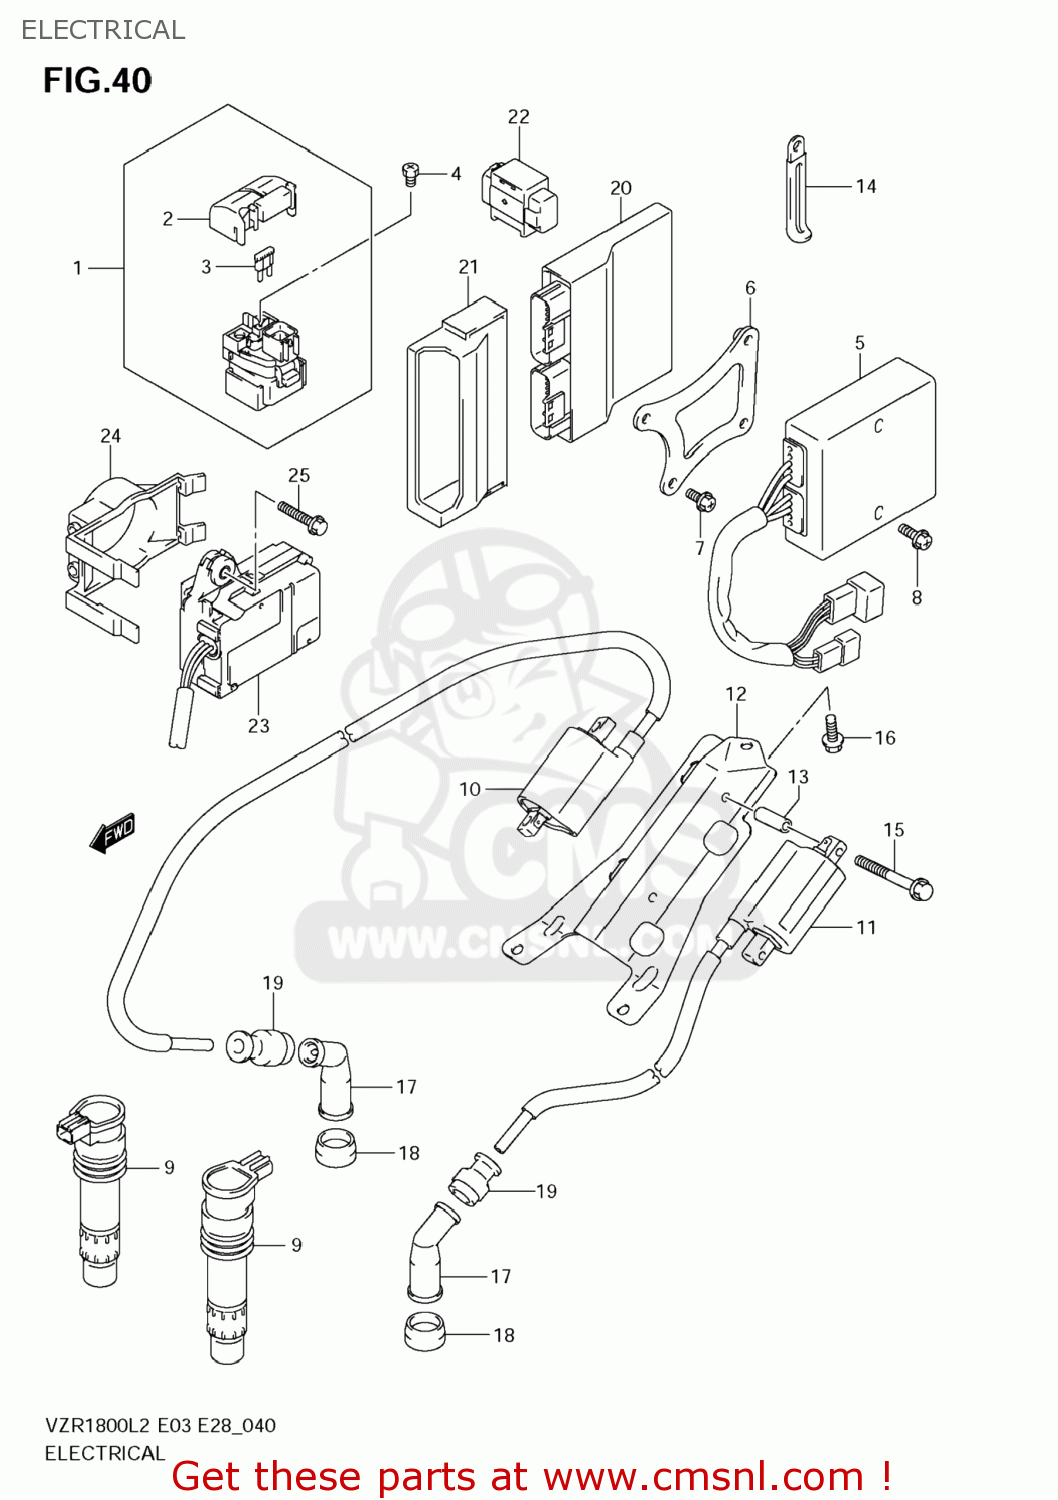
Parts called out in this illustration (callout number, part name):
1	RELAY ASSY,STARTING MOTOR
2	COVER
3	FUSE(30A)
4	SCREW(6X8)
5	RECTIFIER ASSY
6	BRACKET,RECT FIG
7	SCREW
8	SCREW
9	COIL ASSY,IGNITION
10	COIL ASSY,IGNITION RR
11	COIL ASSY,IGNITION RR
12	BRACKET,IGNITION COIL
13	SPACER(6.4X10X18)
14	CLAMP(L:80)
15	BOLT
16	BOLT
17	CAP ASSY,SPARK PLUG
18	SEAL,SPARK PLUG
19	SEAL,HIGH TENSION CORD
20	CONTROL UNIT,FI
21	HOLDER,FI CONTROL UNIT
22	SENSOR ASSY,FUEL CUT
23	ACTUATOR ASSY,EXHAUST CONTROL
24	COVER,ACTUATOR
25	BOLT
